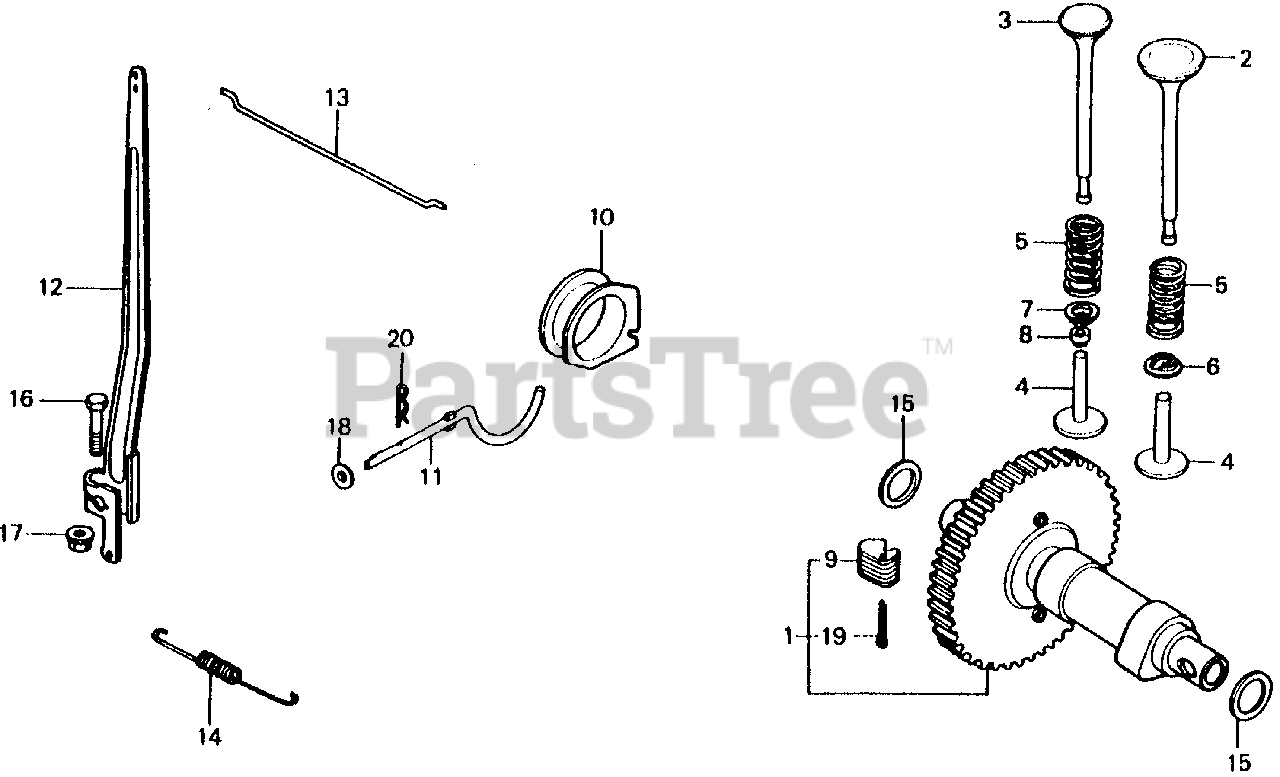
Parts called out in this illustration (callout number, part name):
1	CAMSHAFT ASSY.
2	VALVE, IN.
3	VALVE, EX.
4	LIFTER, VALVE (45.89MM)
4	LIFTER, VALVE (46.04MM)
4	LIFTER, VALVE (46.19MM)
4	LIFTER, VALVE (46.34MM)
5	SPRING, VALVE
6	RETAINER, VALVE SPRING
7	RETAINER, VALVE SPRING
8	ROTATOR, EX. VALVE
9	WEIGHT, GOVERNOR
10	SLIDER, GOVERNOR
11	SHAFT, GOVERNOR
12	ARM, GOVERNOR
13	ROD, GOVERNOR
14	SPRING, GOVERNOR
15	WASHER, THRUST (18MM)
16	BOLT, GOVERNOR ARM
17	NUT, FLANGE (6MM)
18	WASHER, PLAIN (6MM)
19	PIN, COTTER (3.0X45)
20	PIN, LOCK (10MM)
